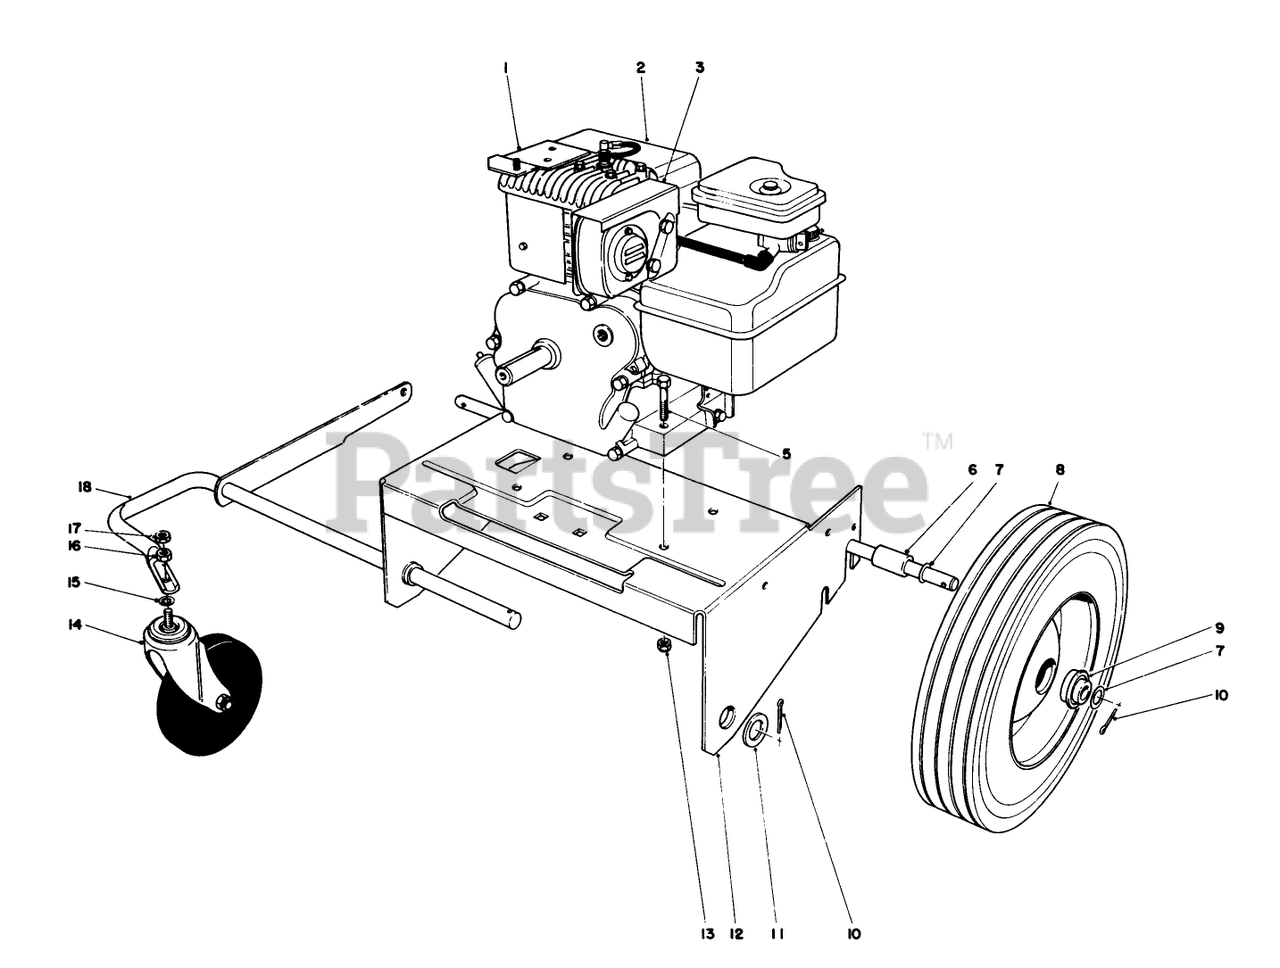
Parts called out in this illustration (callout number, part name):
1	Mounting Bracket
2	ORDER FROM BRIGGS
3	HEAT SHIELD
5	SCREW-HH
6	SPACER-AXLE
7	WASHER
8	WHEEL
9	BEARING
10	PIN-COTTER
11	WASHER-FLAT
13	NUT-LOCK, CONE
14	CASTER
15	Lockwasher
16	NUT-HH
